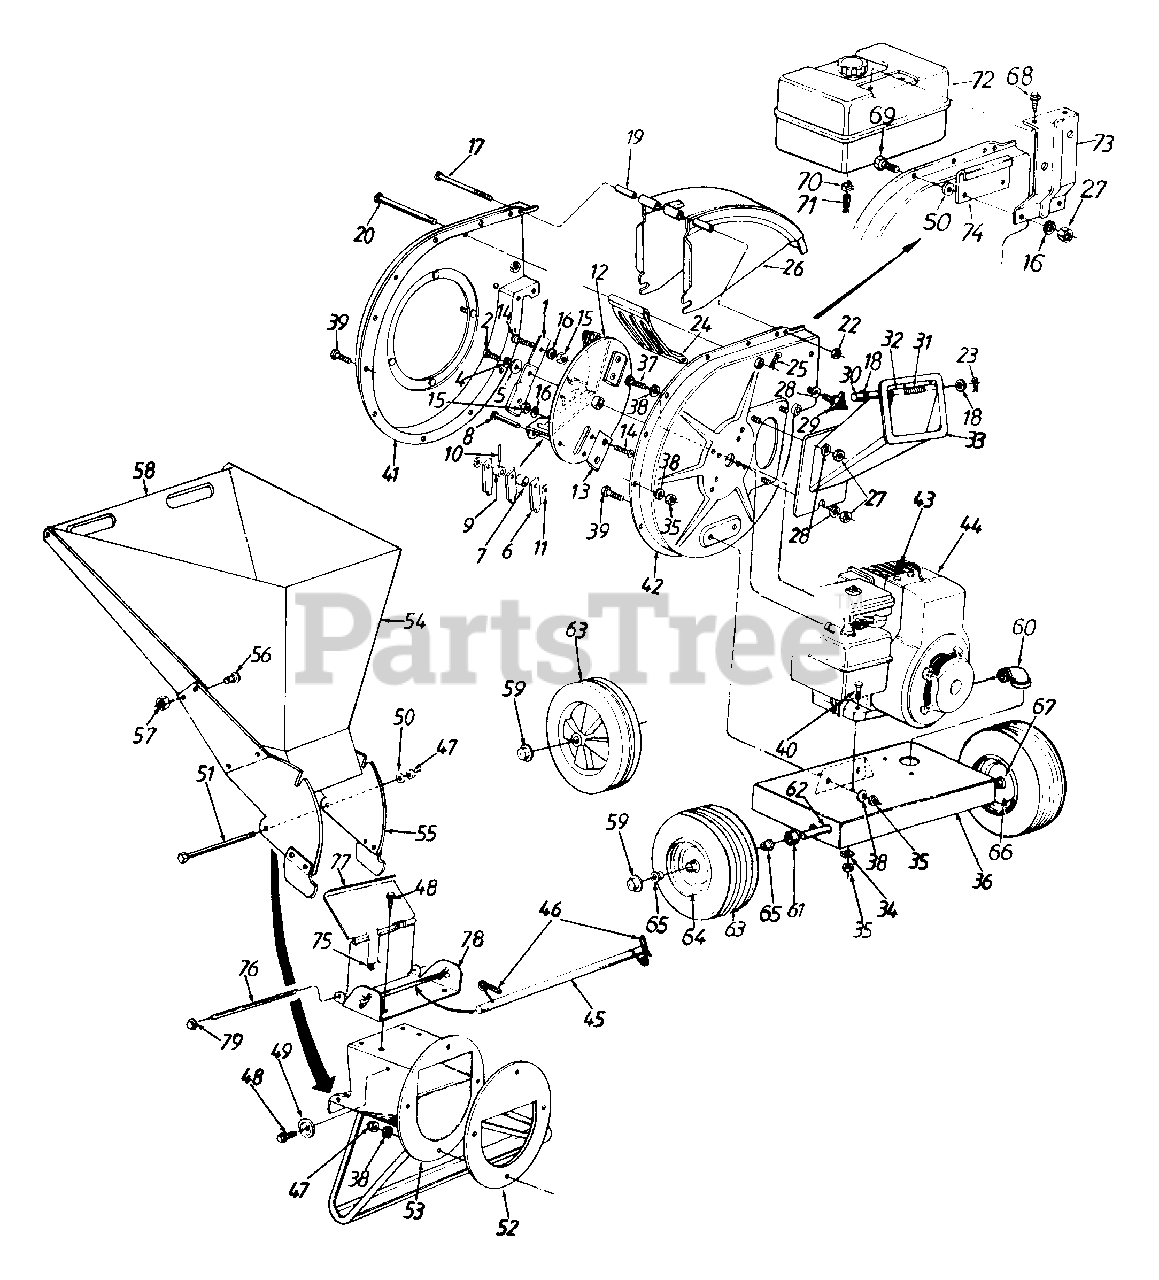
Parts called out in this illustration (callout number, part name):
1	Blade
2	Hex Patch Bolt 3/8-24 x 2.25" (Gr. 8)
4	L-Wash. 3/8" I.D. H.D.
5	Fl-Wash. .406" I.D. x 1.25" O.D. Hdn.
6	Flail
7	Flail Spacer
8	Clevis Pin .496" Dia.
9	Flail Spacer w/.160" Dia. Hole
10	Spring Roll Pin 1.12" Lg.
11	Fl-Wash. .531" I.D. x .94" O.D.
12	Impeller Ass'y. Comp.
13	Chipper Blade
14	Flat Hd. Scr. 5/16-24 x .75" Lg.
15	Hex Top L-Nut 5/16-24 (Gr. 5)
16	L-Wash. 5/16" I.O.
17	Hex Bolt 1/4-20 x 3.75" Lg.
18	Fl-Wash. .281" I.D. x .5" O.D.
19	Chute Hinge Spacer 1.66" Lg.
20	Clevis Pin .5" Dia. x 4.62" Lg.
22	Hex Ctr. L-Nut 1/4-20 Thd.
23	Cotter Pin
24	Shredder Screen
25	Internal Cotter Pin 3/8" Dia.
27	Hex Nut 5/16-18 Thd. (Gr. 5)
28	Bell-Wash. .345" I.D. x .88"
29	Hand Knob
30	Chipper Door Rod
31	Torsion Spring 1.14" Lg.
35	Hex Nut 5/16-18 Thd. (Gr. 5)
38	L-Wash. 5/16" I.D.
39	Hex Bolt 5/16-18 x .75" Lg. (Gr. 5)
40	Hex Bolt 5/16-18 x 1.75" Lg.
44	Engine
45	Release Bar
46	Torsion Spring 1.06" Lg.
47	Elastic Lock Nut 5/16-18 Thd.
48	Hex Wash. Hd. Self-Tap Scr. 5/16-18 x .75" Lg.
49	Stop Washer
50	Fl-Wash. 5/16" I.D.
51	Hex Bolt 5/16-18 x 8.38" Lg.
57	Hex L-Nut 1/4-20 Thd.
58	Upper Leaf Ramp Section
59	Push Cap 5/8" Dia. Rod
60	Drain Elbow
61	Spacer .64" I.D. x .38" Lg.
62	Shredder Axle
63	Wheel Ass'y. Comp.
66	Air Valve
67	Grease Fitting
68	Hex Hi - Low Scr. 1/4" x .75" Lg.
69	Hex Bolt 5/16-18 x .88" Lg.
70	Hose Clamp
71	Fuel Line - 7" Lg.
72	Fuel Tank Ass'y. Comp.
75	Torsion Spring
76	Hopper Door Rod
